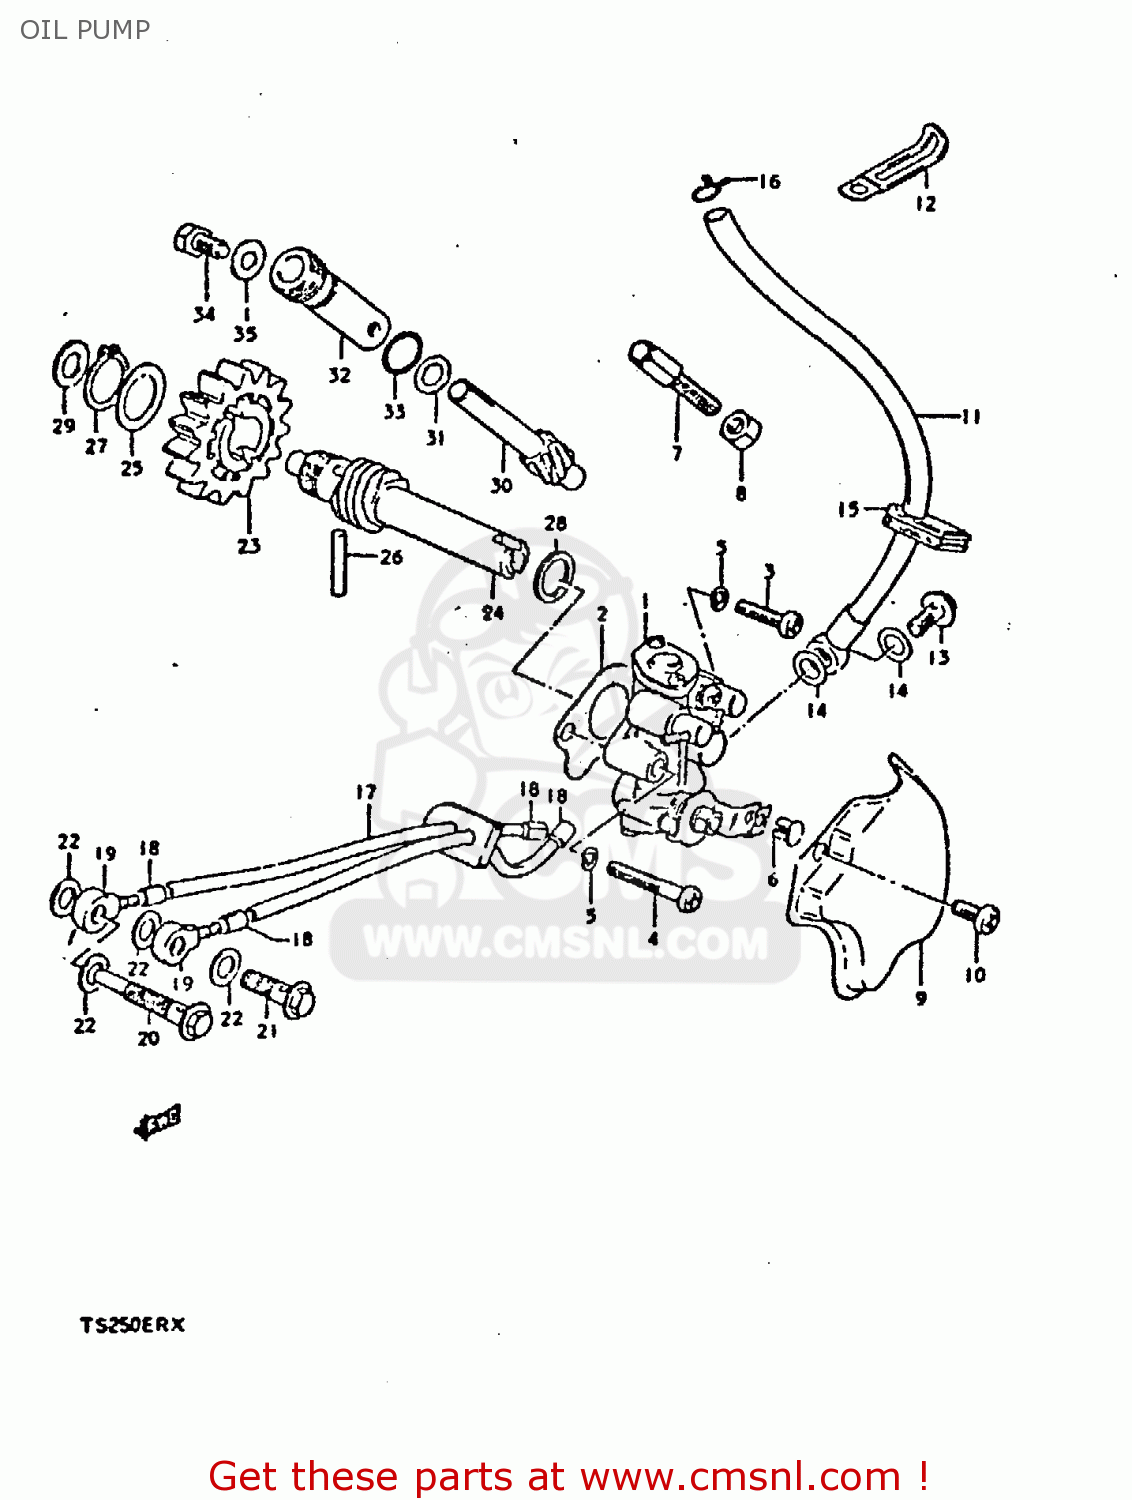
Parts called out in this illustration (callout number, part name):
1	PUMP ASSEMBLY,OIL
2	GASKET,OIL PUMP (NAS)
3	SCREW
4	SCREW
5	LOCK WASHER
6	TERMINAL,CABLE
7	BOLT
8	NUT
9	CAP,OIL PUMP INSPECTION
10	SCREW
11	HOSE,OIL NO.1
12	CLAMP
13	UNION BOLT
14	GASKET(6.2X11X1).2 (NAS)
15	GROMMET
16	CLIP
17	HOSE,OIL NO.2
18	CLIP
19	UNION
20	UNION
21	UNION BOLT
22	GASKET(6.2X11X1).2 (NAS)
23	GEAR,OIL PUMP DRIVE
24	SHAFT,OIL PUMP IDLE GEAR
25	WASHER, INNER
26	ROLLER(4X23.8)
27	CIRCLIP
28	WASHER
29	THRUST WASHER
30	GEAR,TACHOMETER DRIVEN
31	WASHER(8X13.7X1)
32	SLEEVE,TACHOMETER DRIVE
33	O RING(D:1.3,ID:9.6)
34	BOLT
35	WASHER
